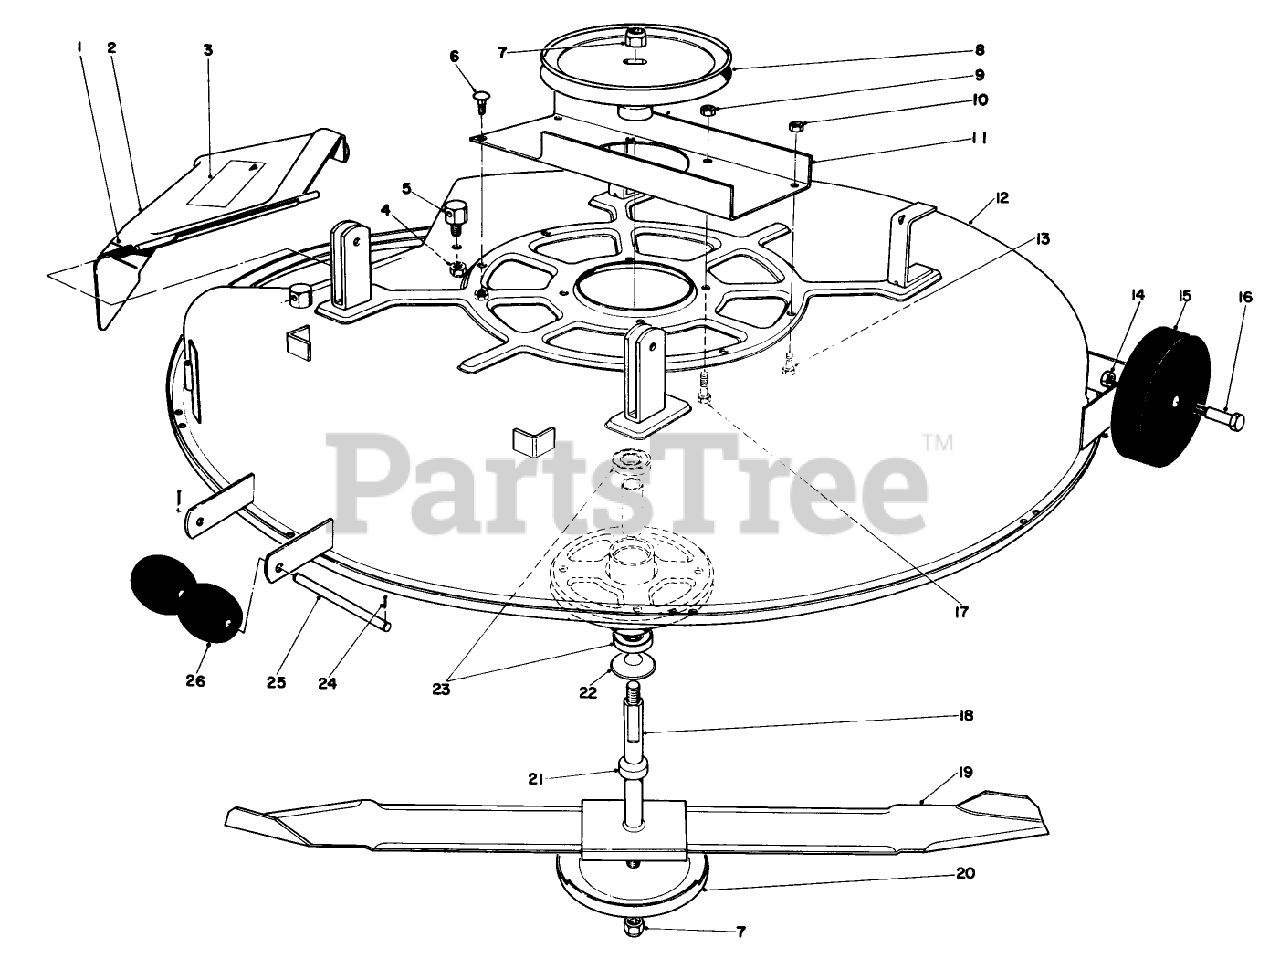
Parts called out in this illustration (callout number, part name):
1	SPRING
2	Deflector Assembly (Incl. Ref. #3)
3	Decal
4	NUT-LOCK, SIDE
5	POST-PIVOT
6	SCREW-CARR
8	PULLEY(BLADE DRIVE)
9	NUT-LOCK, CONE
11	REINFORCEMENT CHANNEL
12	Cutter Deck
13	SCREW-HH
14	Nut
15	DECK WHEEL
17	SCREW-HH
18	Spindle Assembly (Incl. Ref. #21-23)
19	Blade
20	Cup
21	SPACER
22	DUST COVER
23	BEARING
24	PIN-COTTER
25	ROLLER SHAFT
26	Roller
